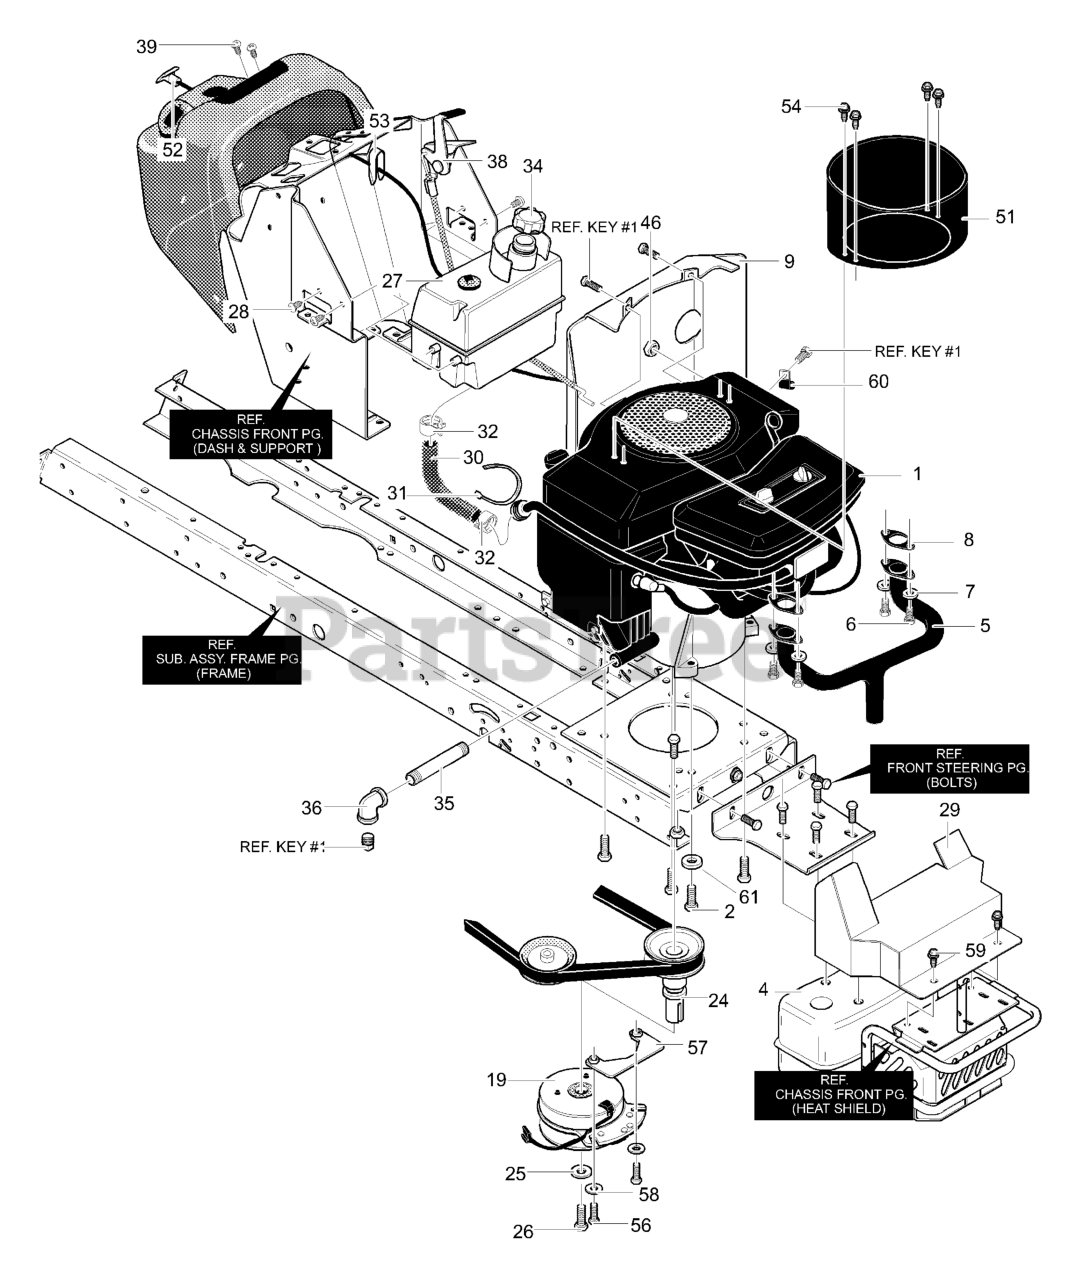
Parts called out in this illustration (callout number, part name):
1	ENGINE
2	BOLT
4	MUFFLER, TWIN-CYLINDER
5	MANIFOLD, EXHAUST
8	GASKET, MUFFLER
9	SHIELD, HEAT
18	SCREW
19	CLUTCH, ELECTRIC
24	PULLEY, ADAPTER
25	WASHER
27	FUEL TANK
29	ASSEMBLY, SHIELD
30	LINE, FUEL
31	TIE, CABLE
32	CLAMP, FUEL LINE
34	FUEL CAP
35	TUBE, OIL DRAIN
36	OIL DRAIN
38	THROTTLE CONTROL
39	SCREW
51	PLENUM
53	CLIP, CHOKE CONTROL
57	PLATE, BRAKE
58	WASHER
59	SCREW
60	RETAINER, WIRE
61	WASHER
